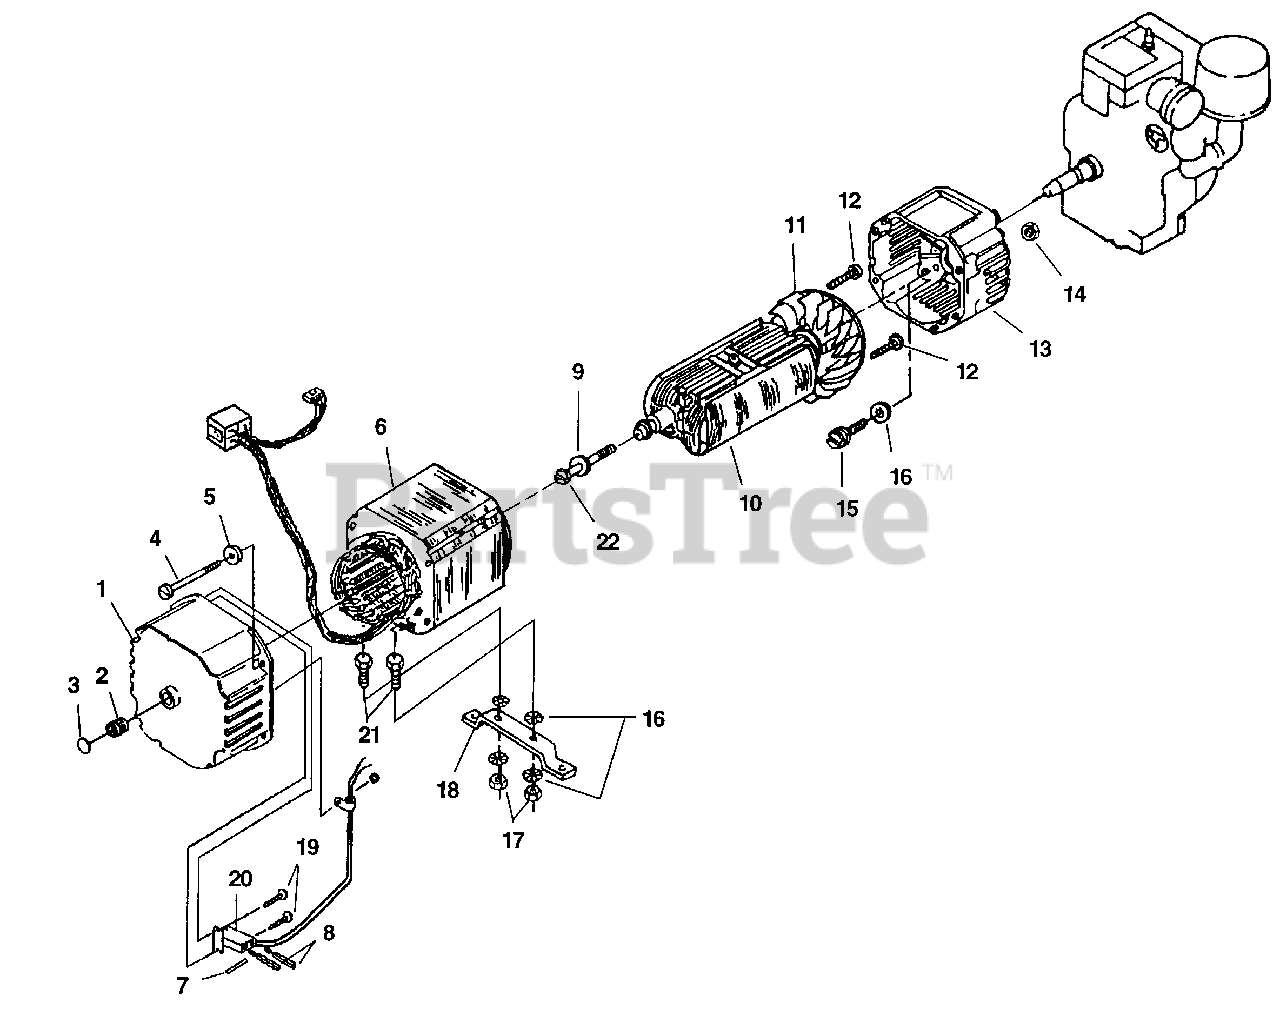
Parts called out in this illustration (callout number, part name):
1	Complete Brush Head
2	Bearing - Needle
3	Plug - Expansion
4	Bolt - Stator
5	Washer - Flat (1/4")
6	Stator & Harness
8	Brush
9	Washer - Lock (5/16")
11	Fan - Generator
12	Screw - Pan Hd. (6-19 X 3/4")
13	End Bell
14	Nut - Hex (1/4-20)
15	Screw - Hex Hd. (5/16-24 X 3/4")
16	Washer - Lock
17	Nut - Hex (5/16-18)
18	Bracket - Generator Support
19	Screw - Plastite (6-19 X 3/4")
20	Brush Holder
21	Screw - Hex Hd. (5/16-18 X 3/4")
22	Bolt - Rotor
